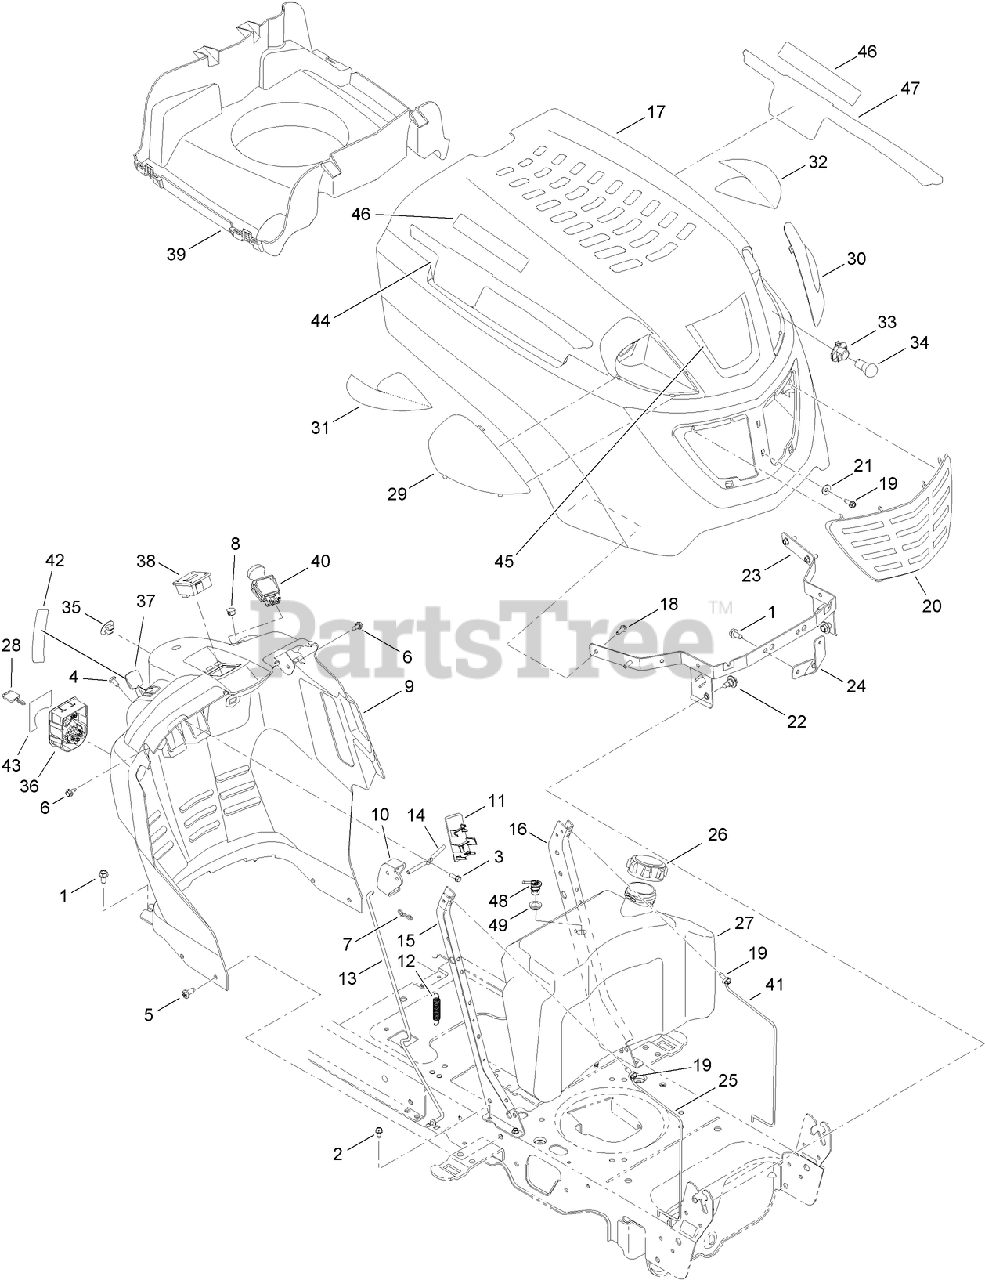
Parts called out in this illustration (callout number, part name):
1	SCREW-TAP
2	SCREW-HWHTF
3	SCREW-TAP
4	SCREW-TAP
5	SCREW-TAP
6	SCREW-HWH
7	PIN-COTTER
8	CAP-PLUG, HOLE
9	DASH-ELECTRIC, PTO
10	LEVER-DASH
11	COVER-CRUISE
12	SPRING-EXTENSION
13	ROD-LATCH
14	ROD-LEVER, BENT
15	SUPPORT-DASH, PLATE (RH)
16	SUPPORT-DASH, PLATE (LH)
19	SCREW-TAP
21	WASHER-FLAT
22	BOLT-SHOULDER, TAP
23	BRACKET-PIVOT
24	BRACKET-SUPPORT, HOOD
25	ROD-SUPPORT
26	CAP-FUEL
27	TANK-FUEL
28	KEY-IGNITION
29	LENS-RH
30	LENS-LH
31	REFLECTOR-RH
32	REFLECTOR-LH
33	SOCKET-HEADLIGHT
34	LAMP-12V, MINIATURE
35	PLUG-CHOKE
36	MODULE-SWITCH, IGNITION
37	CABLE-THROTTLE AND CHOKE
38	METER-HOUR
39	PLENUM-HOOD
40	SWITCH-ELECTRIC, PTO
41	ROD-SUPPORT, LH TANK
42	DECAL-THROTTLE
44	DECAL-HOOD, RIGHT SIDE
45	DECAL-HOOD
47	DECAL-HOOD, LEFT SIDE
48	VALVE, ROLLOVER GROMMET
49	GROMMET, RUBBER, 23.0 ID
